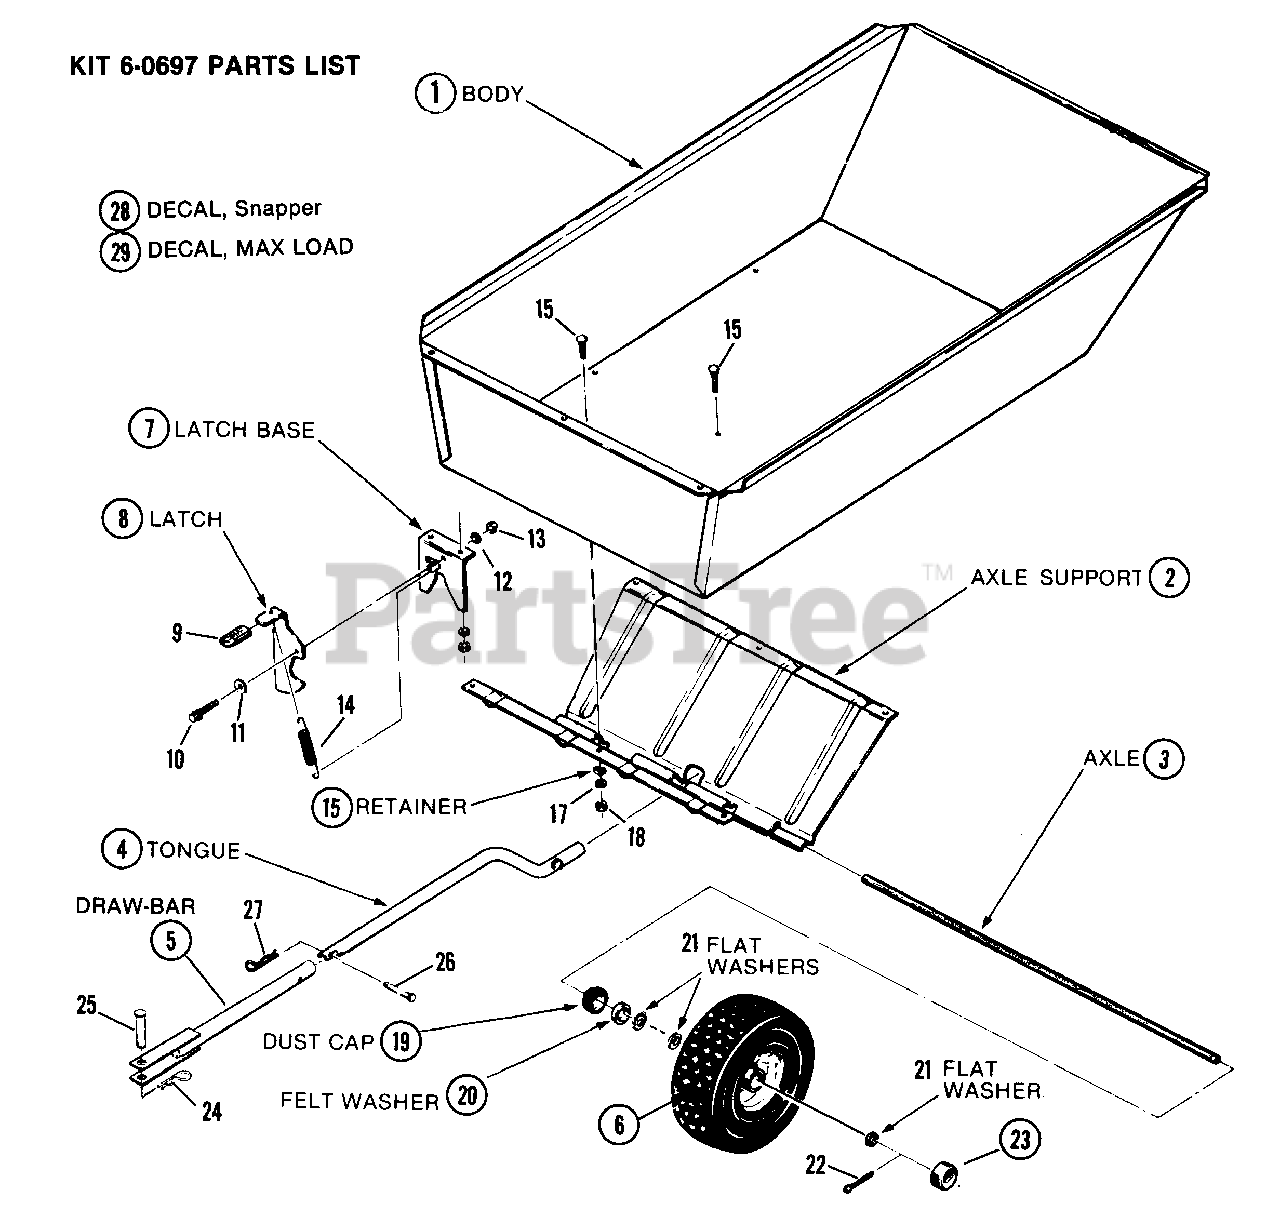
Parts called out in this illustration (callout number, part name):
1	BODY, Dump Wagon
2	SUPPORT, Axle
3	AXLE
4	TONGUE
5	DRAW-BAR
6	ASSEMBLY, Tire & Rim
7	BASE, Latch (Yoke)
9	GRIP, Latch
10	BOLT, 5/16-18 Shoulder
11	WASHER, Spring
12	LOCKWASHER, 5/16 Split
13	NUT, 5/16-18 Hex
14	SPRING, Latch
15	BOLT, 1/4-20x3/4 Carriage
17	LOCKWASHER, 1/4 Intern
18	NUT, 1/4-20 Hex
19	DUST CAP
20	WASHER, Felt
21	WASHER, Flat
22	COTTER-PIN, 5/32x1"
23	HUB-CAP
24	CLEVIS-PIN, 1/2-2
25	HAIR-PIN, 1-7/16
26	CLEVIS-PIN, 3/8x2-1/4
27	HAIR-PIN, 3/32x1-7/8
28	DECAL, Snapper
29	DECAL, MAX LOAD Warn
